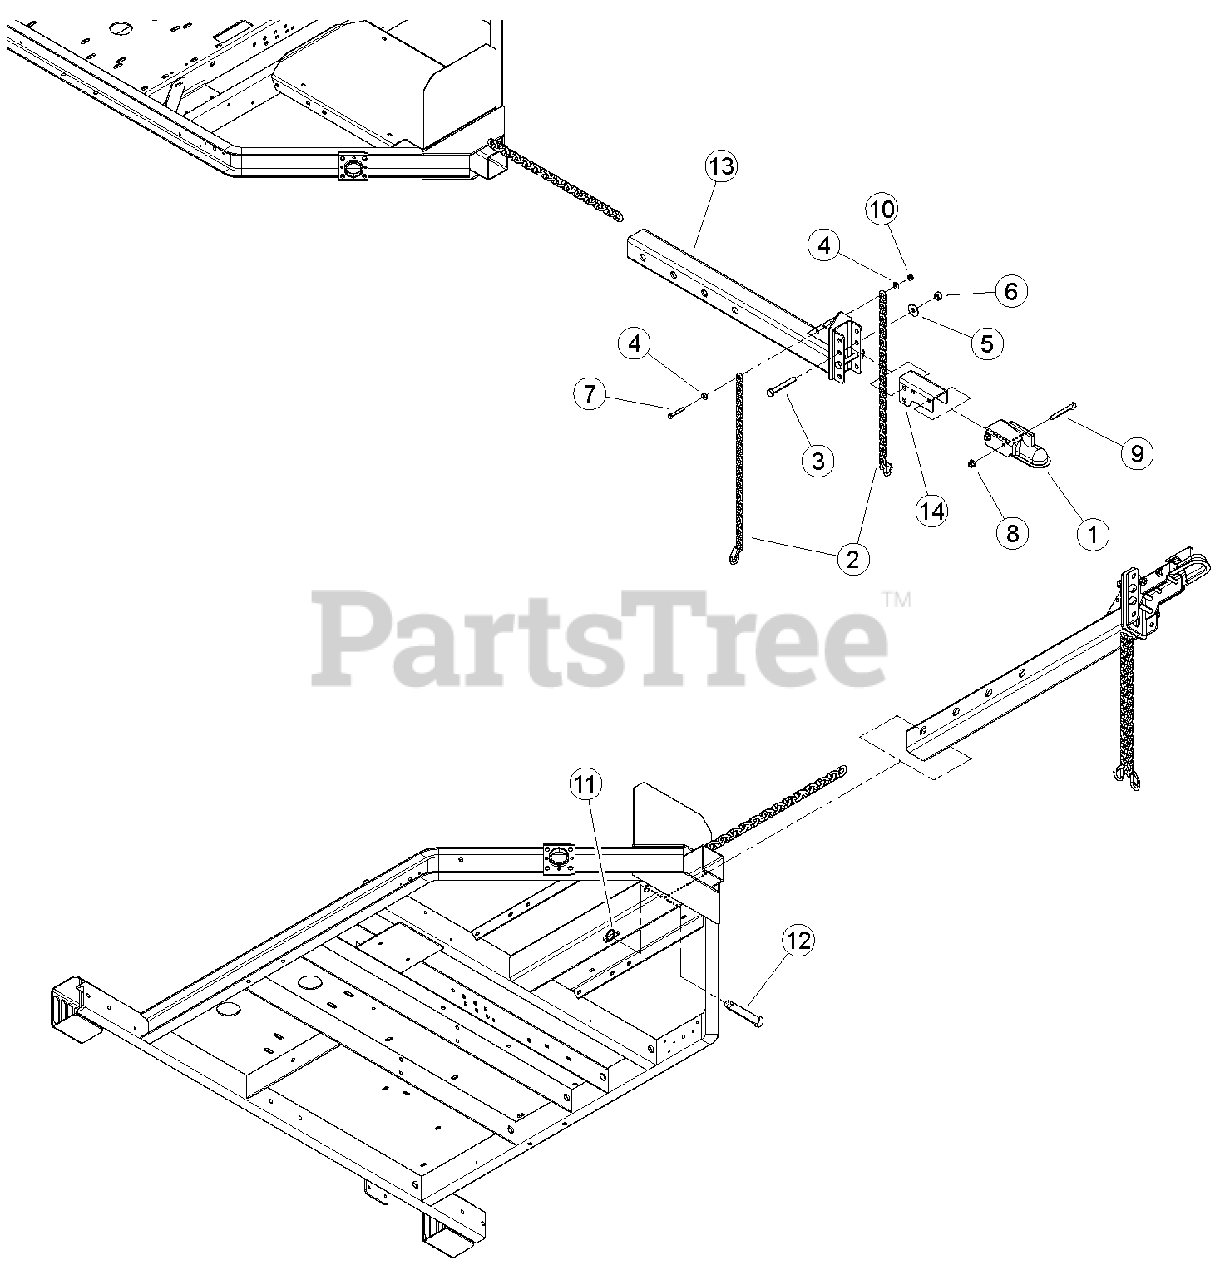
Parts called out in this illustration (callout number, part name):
1	COUPLER, 2 IN
2	CHAIN, SAFETY 5000 LB W/ LATCH
3	BOLT, 5/8 X 4-1/2 HEX HD G5 ZP
4	WASHER, 3/8" FLAT ZP
5	WASHER, 5/8" FLAT ZP
6	NUT, 5/8" CENTERLOCK ZP GR5
7	BOLT, 3/8 X 2-1/2 GR5 HHCS ZP
8	NUT, 1/2-13 NYLOCK FLANGE
9	BOLT, 1/2-13 X 4 HWH GR5 CZP
10	NUT, 3/8-16 NYLOCK FLANGE
11	PIN, 7/16 X 1-3/4 LYNCH
12	TOP LINK PIN, CAT 2
13	WELDMENT, HITCH POLE W/ PLATE
14	MOUNT, COUPLER
